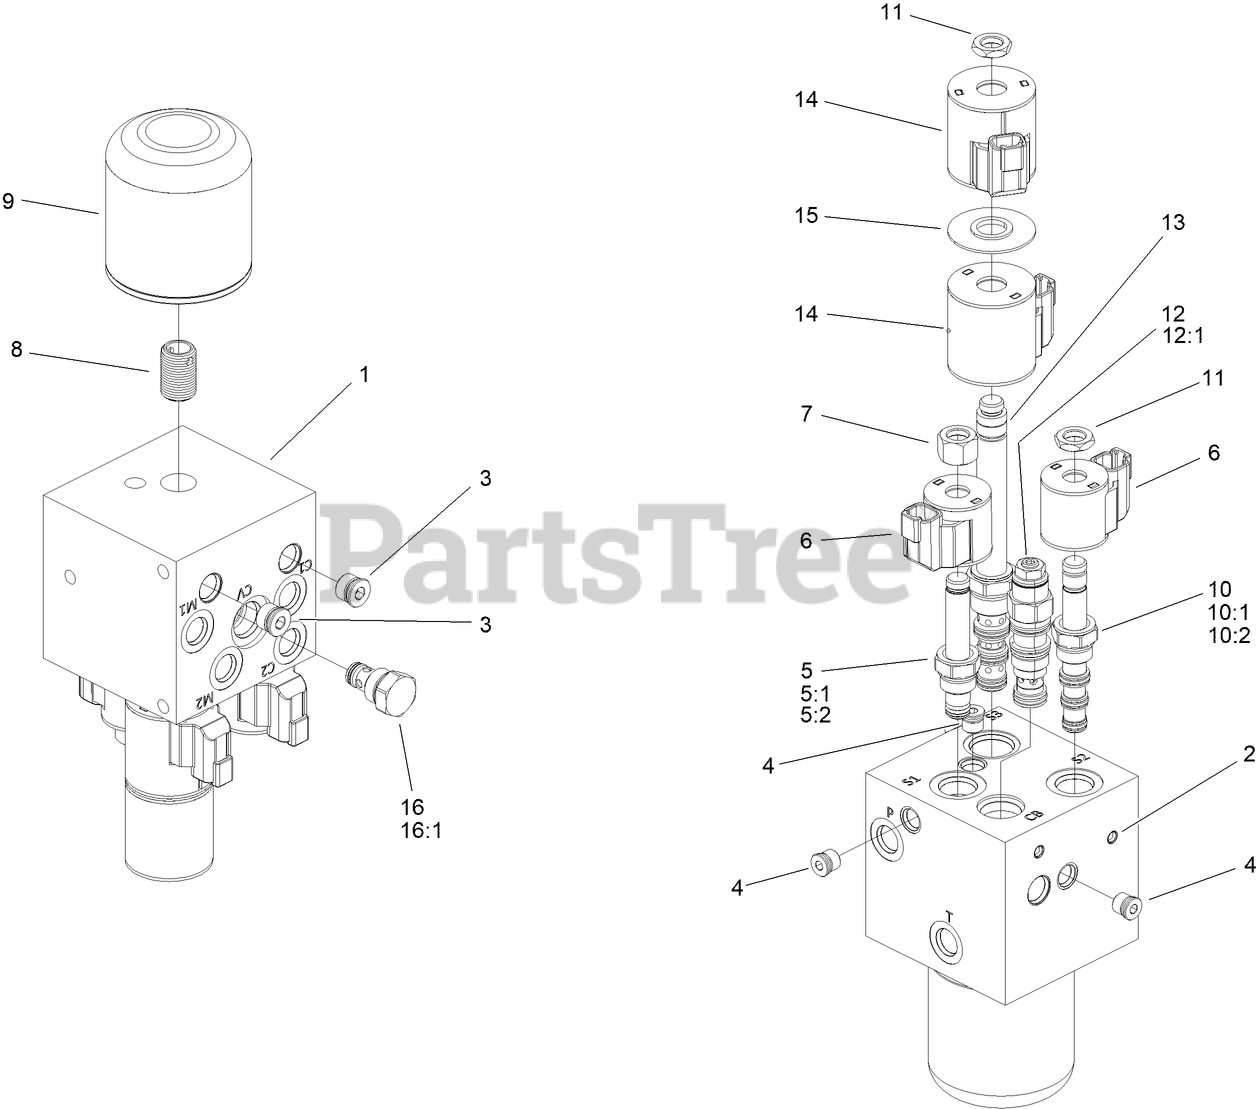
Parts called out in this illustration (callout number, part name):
1	MANIFOLD BLOCK
2	EXPANDER PLUG
5	VALVE-SOLENOID
5:1	SEAL KIT
5:2	NUT-SOLENOID
7	NUT-SOLENOID
8	NIPPLE-FILTER
9	FILTER-OIL, HYD
10	VALVE-SOLENOID
10:1	SEAL KIT
10:2	NUT-COIL
11	NUT-COIL
12	VALVE-BALANCE, COUNTER
12:1	SEAL KIT
13	VALVE-SOLENOID
14	COIL-SOLENOID
15	SPACER-E COIL
16	CHECK VALVE ASM
16:1	SEAL KIT
